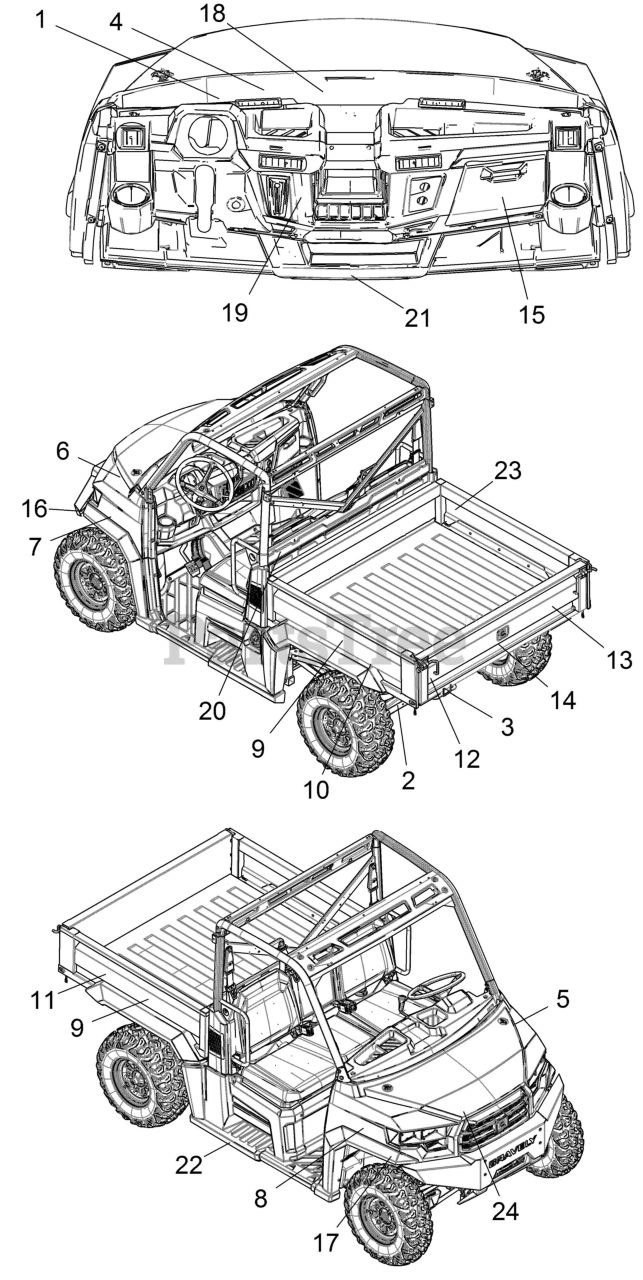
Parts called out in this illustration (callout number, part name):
1	DECAL, AGE WARNING 16
2	DECAL, REFLECTOR RED
3	DECAL-WARNING,TRAILER LOAD
4	LABEL, OPEI COMPLIANCE
5	DECAL, HOOD TOP EFI LH
6	DECAL, HOOD TOP EFI RH
7	DECAL, HOOD SIDE ATLSJSV, LH
8	DECAL, HOOD SIDE ATLSJSV, RH
9	DECAL, BOX SIDE GRAVELY
10	DECAL, BOX SIDE 3000 LH
11	DECAL, BOX SIDE 3000 RH
12	DECAL, TAILGATE ATLSJSV, LH
13	DECAL, TAILGATE AWD RH
14	DECAL, TAILGATE GRAVELY CENTER
15	DECAL, GLOVEBOX COVER
16	DECAL, REFLECTOR AMBER LH
17	DECAL, REFLECTOR AMBER RH
18	DECAL, WARNING DISC GRAVELY
19	DECAL, CAUTION SHIFT/BRAKE
20	DECAL, ROPS GRAVELY 3000
21	DECAL,WARNING PASS/TIRE PRESS
22	DECAL NOT A STEP
23	DECAL, WARN, NEVER CARRY FUEL
24	DECAL-COOLANT
